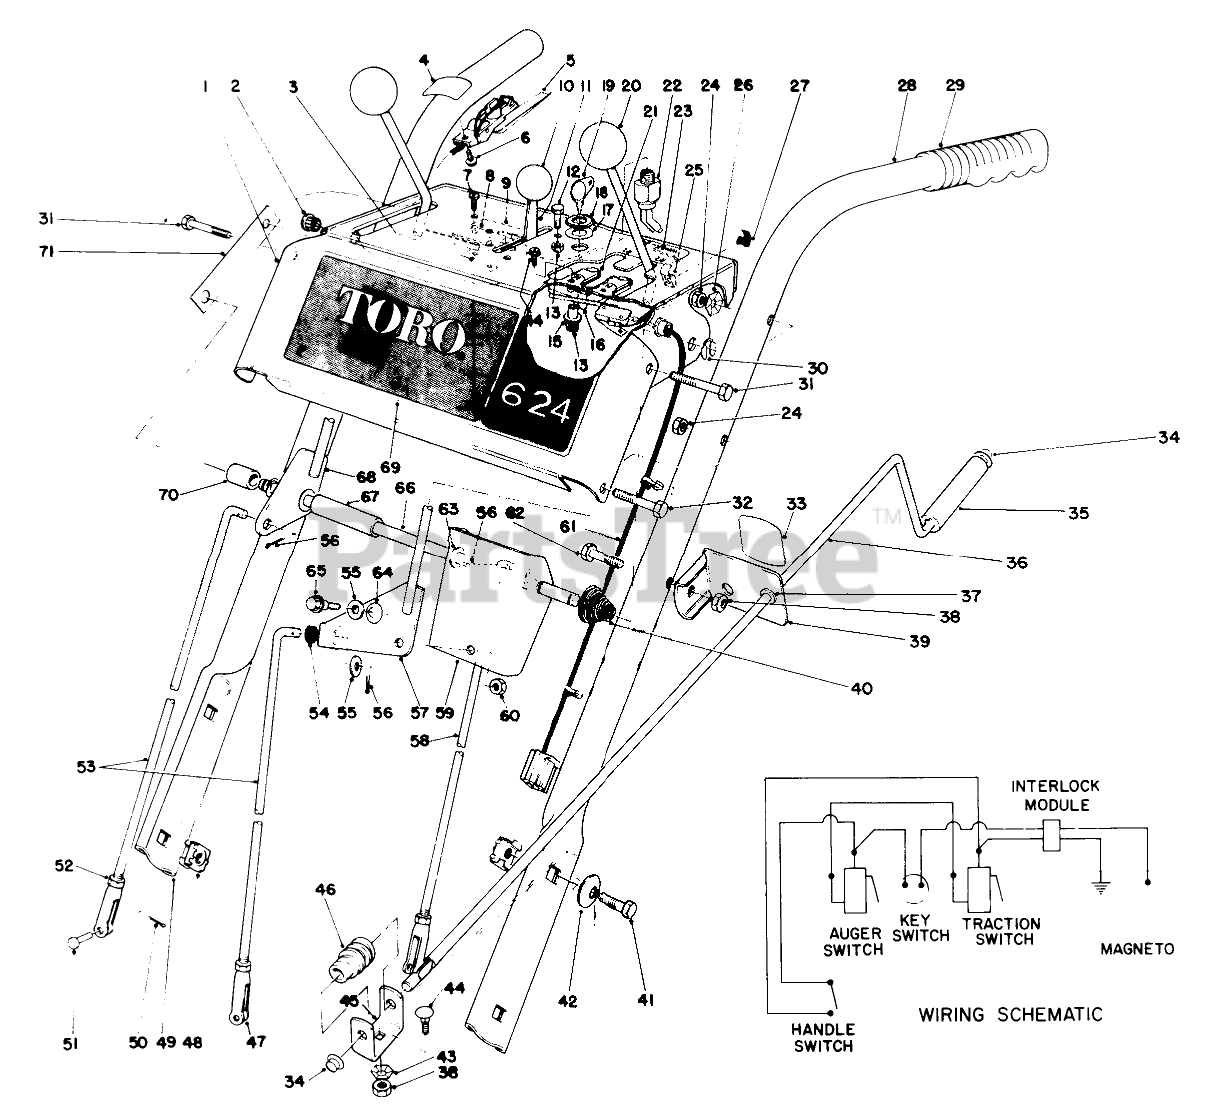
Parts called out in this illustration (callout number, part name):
1	ESCUTCHEON PLT B
2	BUSHING NYLON
3	NUT-SPEED
4	INTERLOCK DECAL
5	INTERLOCK HDLE SWITCH
6	SCREW
7	SCREW-SPH
8	SWITCH-MICRO
9	SWITCH MTG PAD
10	CONTROL KNOB
11	THROTTLE CONTROL
12	HEX HEAD SEMS 10-24X1/2
13	NUT-LOCK, NI
14	10-24 X 7/8 RND HD MS
15	INTERLOCK SPACER
16	INTERLOCK SPRING
17	WASHER-TOOTH, INTERNAL
18	NUT-HH
19	KEY-IGNITION
21	Slide Interlock
22	On-Off Switch (Incl Ref. #17 & 18)
23	INSTR DECAL
24	NUT-LOCK, CONE
25	WIRE CLAMP
26	Washer
27	Mounting Stud
28	LEFT HANDLE
29	Grip Handle
30	RING-CLIP
31	SCREW-HH
32	SCREW-HH
33	DECAL-CHUTE DIRECTION
34	RETAINER-PUSH ON
35	GRIP-CONTROL, CHUTE
36	CHUTE CONTROL ROD
37	Bushing
38	NUT-LOCK, NI
39	Chute Control Rod Mounting (Incl. Ref. #33 & 37)
40	CONICAL SPRING
41	SCREW-HH
42	WASHER-SPRING
43	WASHER-LOCK
44	BOLT-CARR
45	BRACKET-WORM
46	GEAR-WORM, CHUTE
47	CLEVIS
48	Retained Nut
49	HANDLE RIGHT
50	PIN-COTTER
51	PIN-CLEVIS
52	NUT-HJ
53	SPEED SELECTOR ROD
54	GROMMET-RUBBER
55	WASHER-FLAT
56	PIN-COTTER
57	SHIFT LEVER WA
58	TRACTION CONTROL ROD
59	SHIFT BRACKET
60	NUT-LOCK, CONE
61	WIRE HARNESS INTERLOC
62	SCREW-HH
63	WASHER-FLAT
64	7/16 SPRING WASHER
65	SHOULDER SCREW
66	PIVOT ROD
67	SHIFT LEVER SPACER
68	LEVER WA
69	ESCUTCHEON DECAL
70	AUGER LEVER SPACER
71	ESCUTCHEON SUPT STRAP
